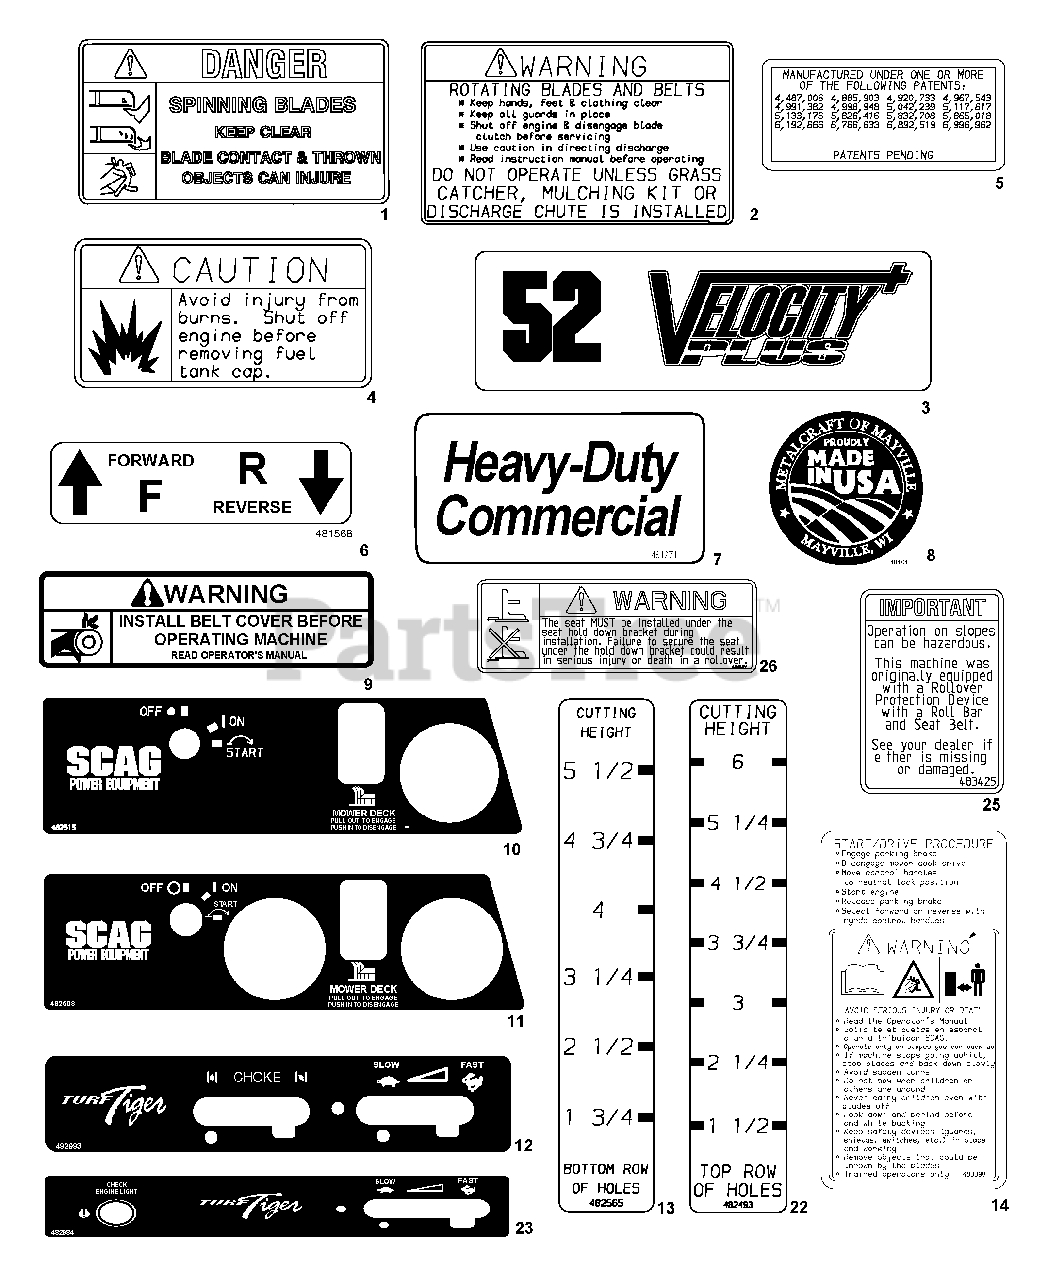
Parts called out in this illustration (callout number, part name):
1	Decal, Danger-Spinning Blades
2	Decal, Warning-Rotating Blades
3	Decal, 52 Velocity Plus
4	Decal, Fuel Tank
5	Decal, Patents
6	Decal, Traction Control
7	Decal, Heavy Duty Commercial
8	Decal, Metalcraft-Made In USA
9	Decal, Belt Cover
10	Decal, Instrument Panel-Upper (Air Cooled)
11	Decal, Instrument Panel-Upper (Kawasaki)
12	Decal, Instrument Panel-Lower
13	Decal, Cutting Height - Lower
14	Decal, Start/Drive Procedure
22	Decal, Cutting Height - Upper
23	Decal, Instrument Panel - Lower
25	Decal, ROPS
26	Decal, Warning Seat Hold Down
